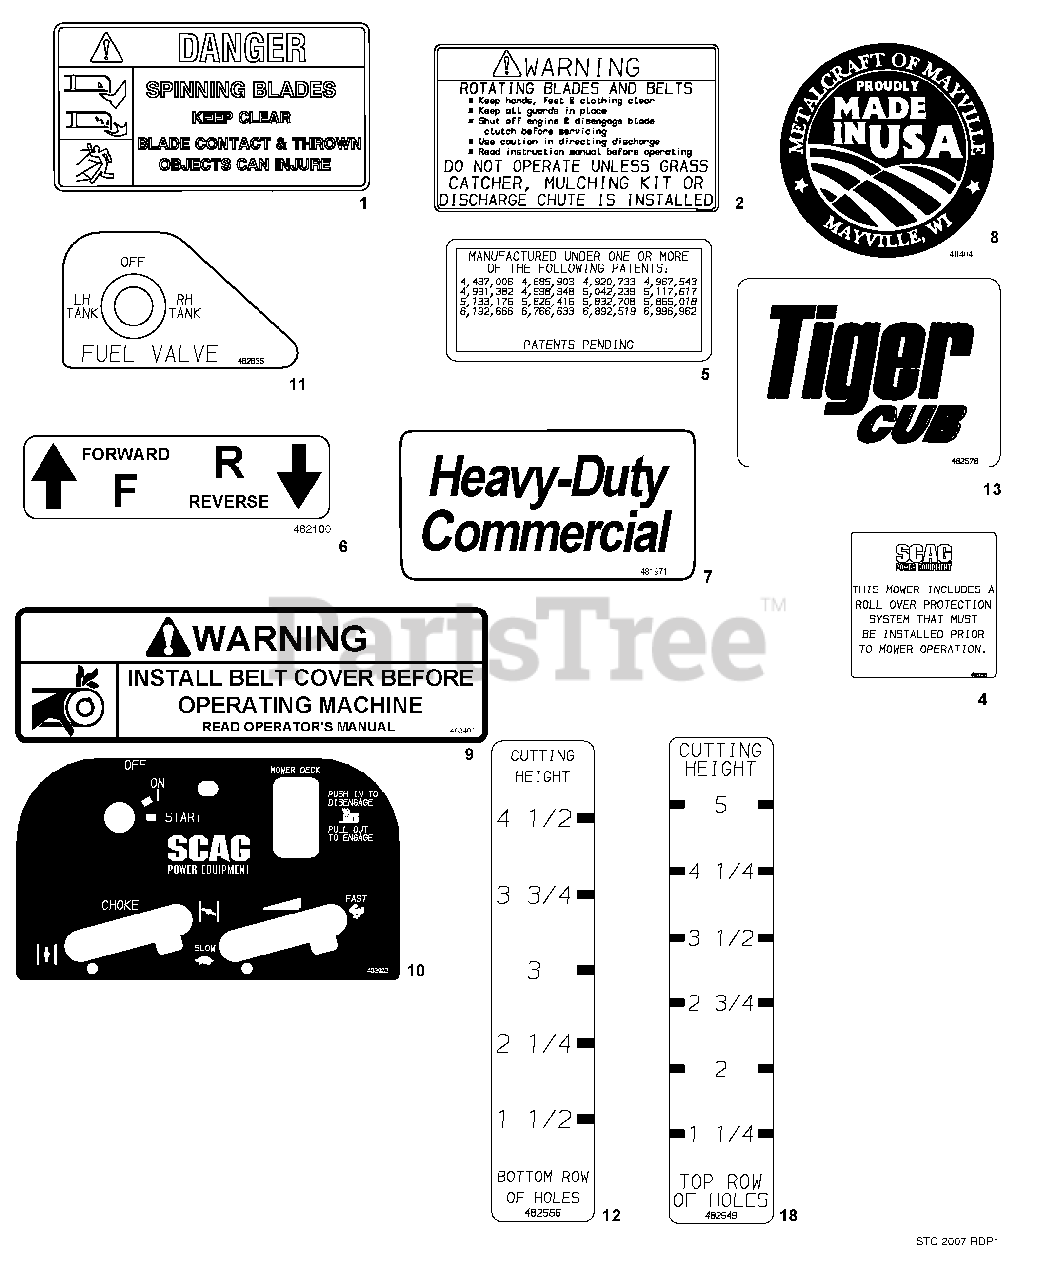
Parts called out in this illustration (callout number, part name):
1	Decal, Danger-Spinning Blades
2	Decal, Warning-Rotating Blades
4	Decal, ROPS
5	Decal, Patents
6	Decal, Traction Control
7	Decal, Heavy Duty Commercial
8	Decal, Metalcraft - Made in USA
9	Decal, Belt Cover
10	Decal, Instrument Panel
11	Decal, Fuel Valve Position
12	Decal, Cutting Height Bottom Row of Holes
13	Decal, Tiger Cub
17	Decal, Discharge Chute
18	Decal, Cutting Height Top Row of Holes
